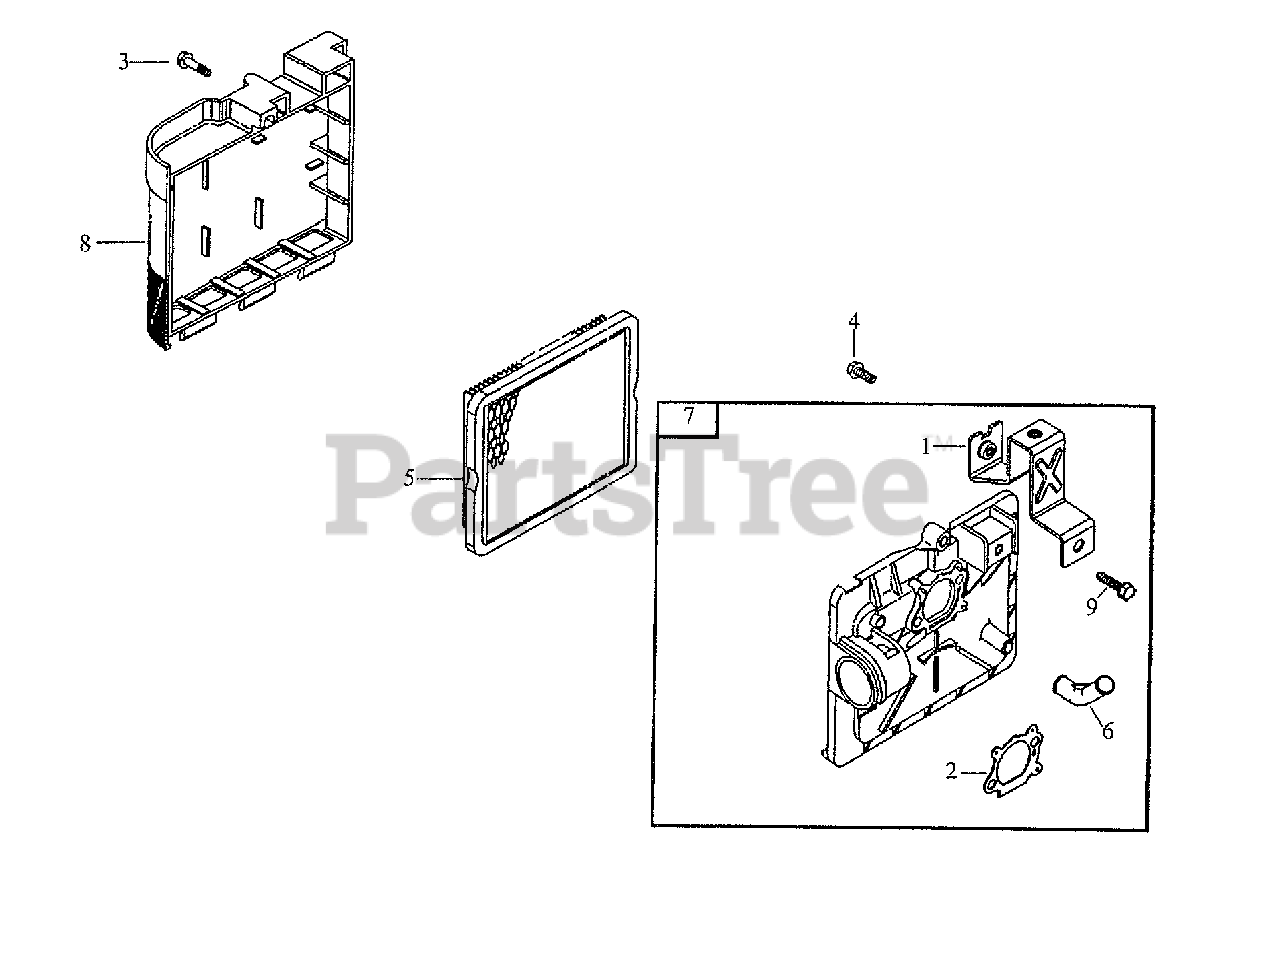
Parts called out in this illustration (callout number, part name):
1	Bracket, Air Cleaner
2	Gasket-Air Cleaner
3	Screw, Cover
4	Screw, Base
5	Filter, Air Cleaner
6	Grommet
7	Base, Air Cleaner
8	Cover, Air Cleaner
9	Screw, Bracket
